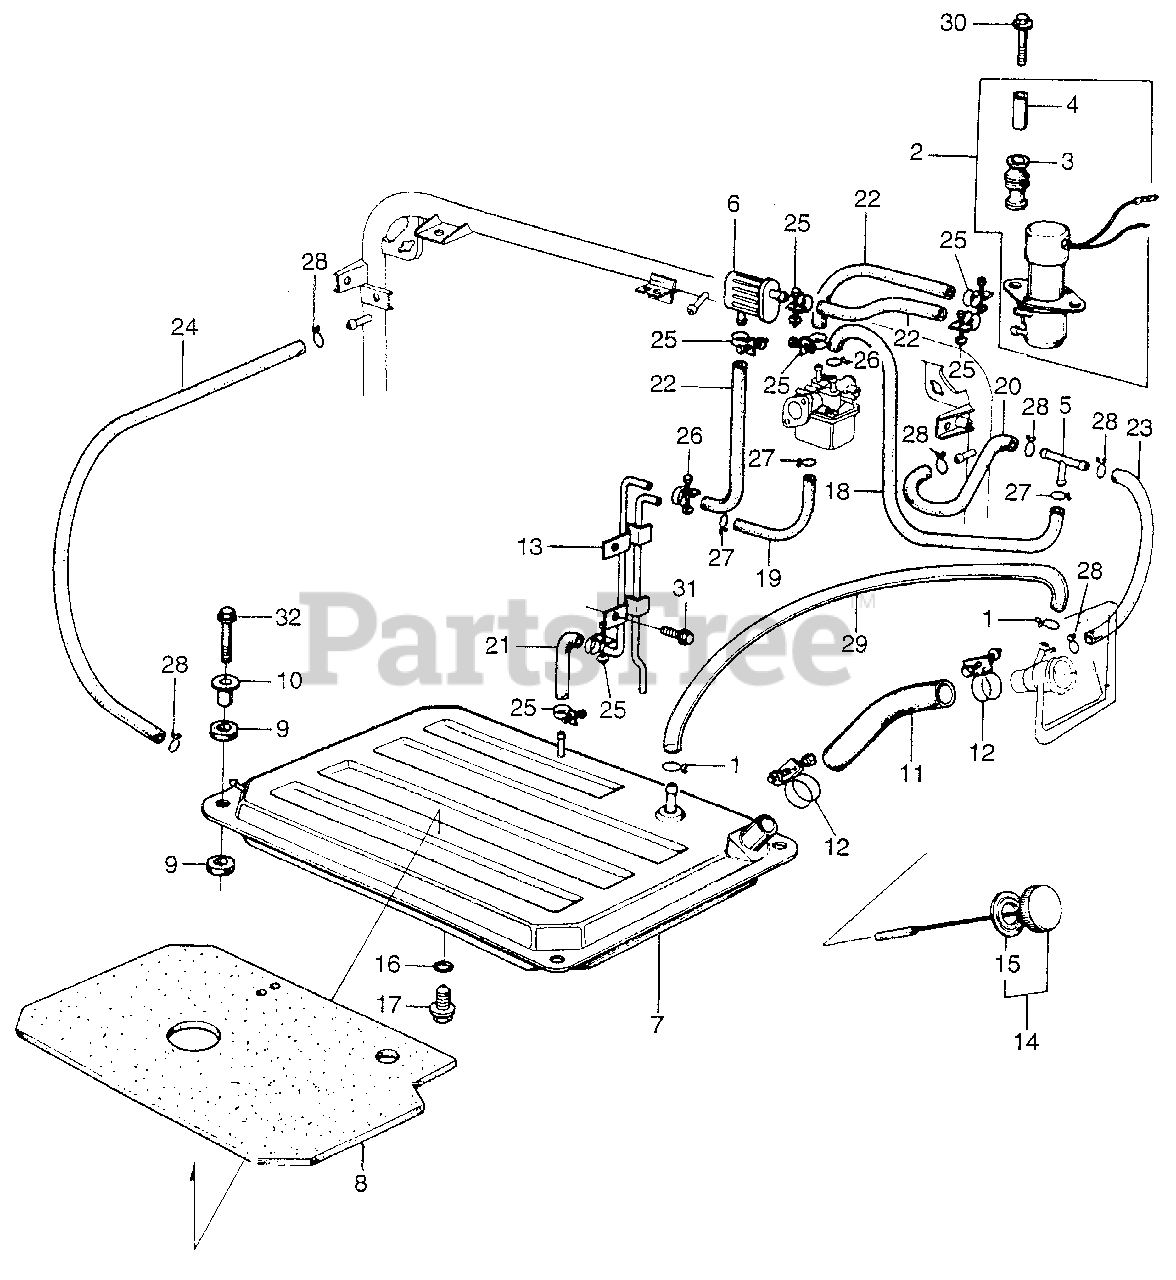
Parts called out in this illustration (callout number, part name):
1	CLIP, BREATHER TUBE (NOT AVAILABLE)
2	PUMP ASSY., FUEL (NOT AVAILABLE)
3	RUBBER, FUEL PUMP SETTING (NOT AVAILABLE)
4	SPACER, FUEL PUMP SETTING
5	JOINT, FUEL RETURN (NOT AVAILABLE)
6	FILTER, FUEL
7	TANK, FUEL
8	SHEET, FUEL TANK
9	RUBBER, FUEL TANK SETTING
10	SUPPORT, FUEL TANK
11	TUBE, FUEL FILLER
12	CLIP, FILLER NECK CONNECTING TUBE
13	PIPE, FUEL
14	CAP, FUEL FILLER (NOT AVAILABLE)
15	GASKET, FILLER (NOT AVAILABLE)
16	O-RING (10x2)
17	BOLT, DRAIN PLUG (12MM)
18	BULK HOSE, FUEL (3.5X3000) (3.5X490)
19	BULK HOSE, FUEL (4.5X3000) (4.5X180)
20	BULK HOSE, FUEL (5.5X8000) (5.5X35)
21	BULK HOSE, FUEL (5.5X8000) (5.5X140)
22	BULK HOSE, FUEL (5.5X8000) (5.5X200)
23	BULK HOSE, FUEL (5.5X8000) (5.5X360)
24	BULK HOSE, FUEL (5.5X8000) (5.5X990)
25	CLIP, TUBE (A12)
26	CLIP, TUBE (B7)
27	CLIP, TUBE (B8)
28	CLIP, TUBE (B10)
29	BULK HOSE, VINYL (12X16X3000) (12X16X350)
30	BOLT, FLANGE (6X28)
31	BOLT, FLANGE (6X12)
32	BOLT, FLANGE (8X32)
